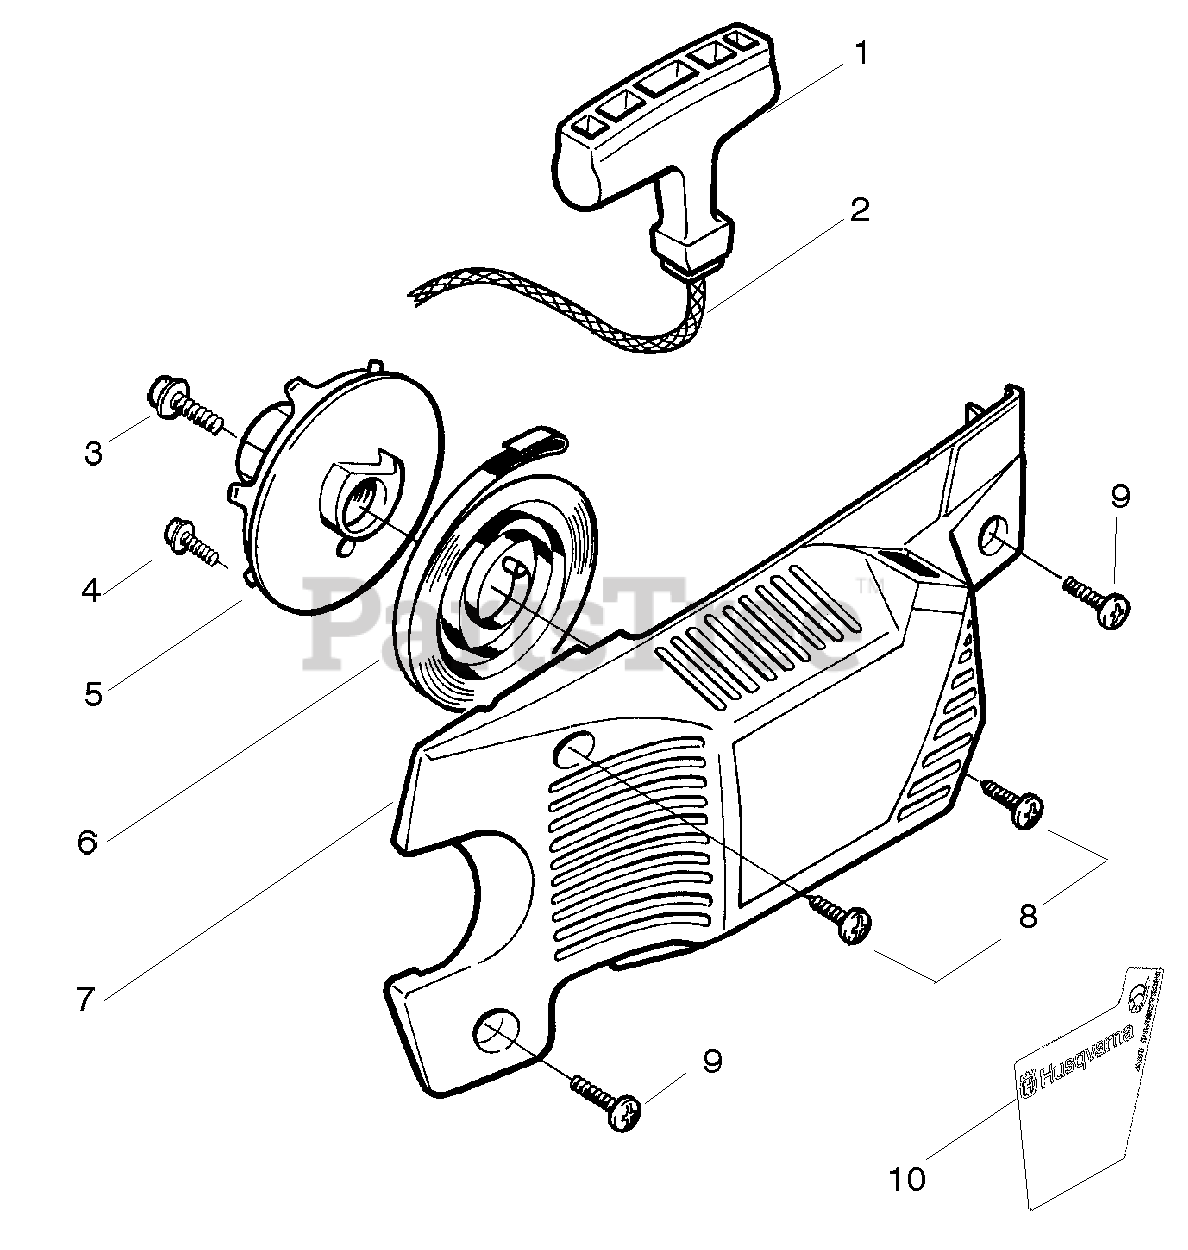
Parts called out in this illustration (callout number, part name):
1	Handle-Starter
5	Kit-Starter Pulley
6	Spring-Recoil
7	Assy-Fan Housing
10	Decal - Fan Housing
